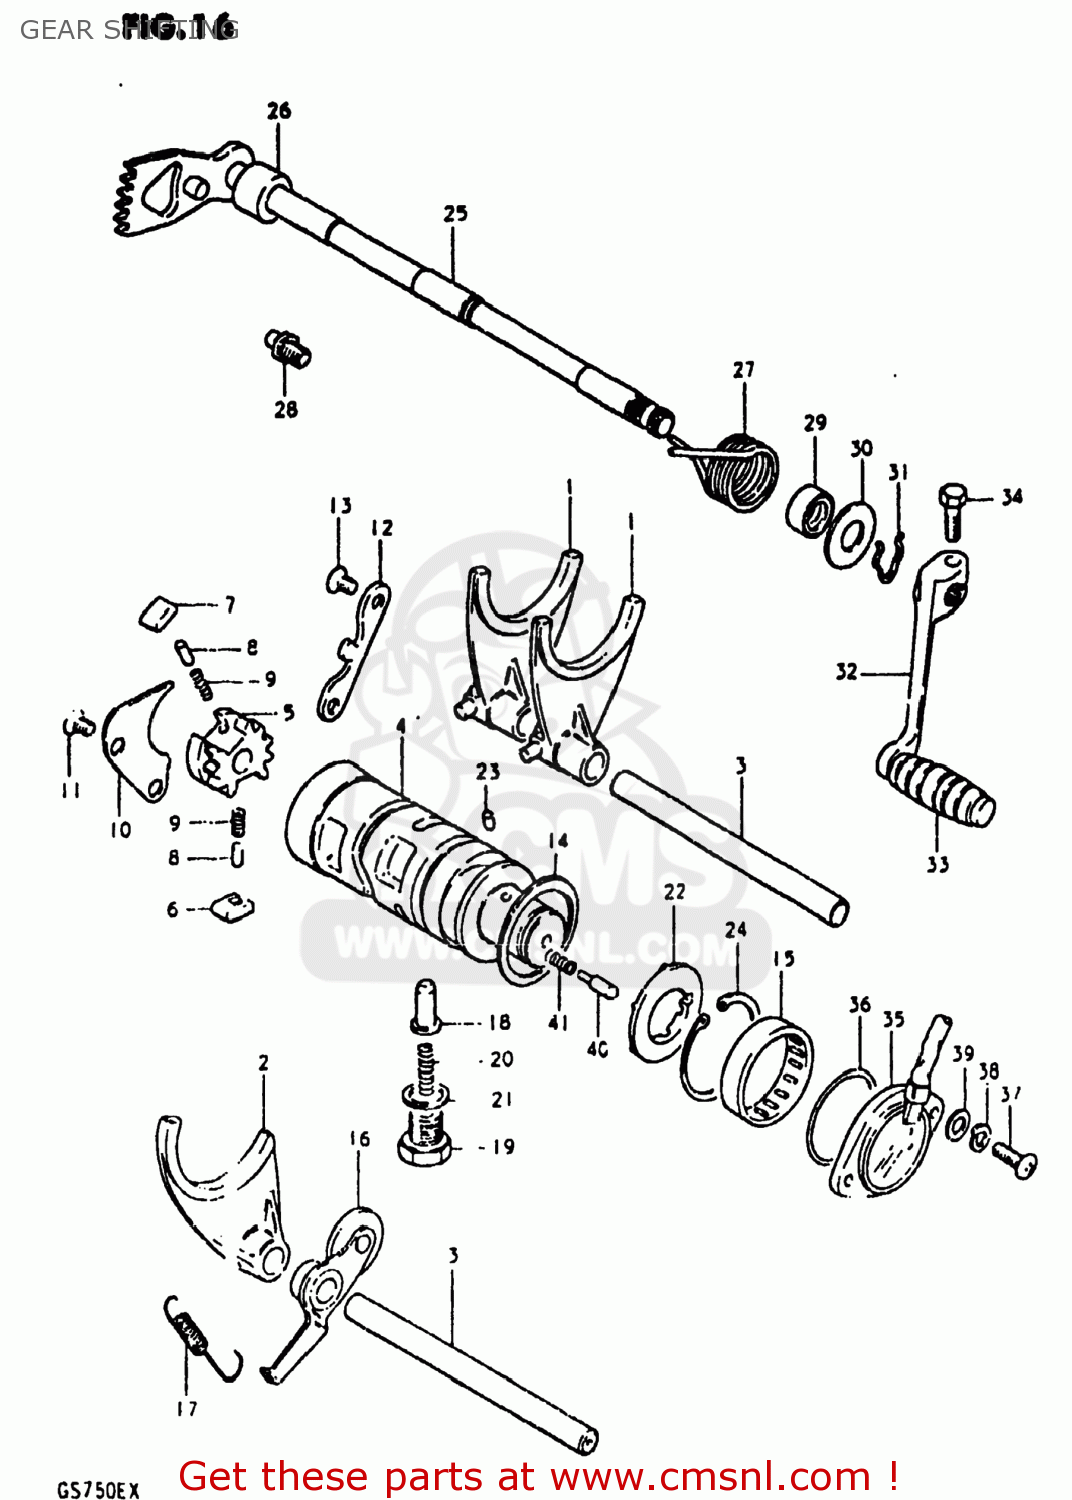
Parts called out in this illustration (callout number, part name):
1	FORK,GEAR SHIFT NO.1
2	FORK,GEAR SHIFT NO.3
3	SHAFT,GEAR SHIFT FORK
4	CAM,GEAR SHIFT
5	RETAINER,GEAR SHIFT CAM
6	PAWL,GEAR SHIFT NO.1
7	PAWL,GEAR SHIFT NO.2
8	PIN(5X8)
9	SPRING
10	LIFTER,GEAR SHIFT PAWL
11	SCREW
12	GUIDE,GEAR SHIFT CAM
13	SCREW
14	WASHER(40X45X1)
15	BEARING(25X32X12)
16	STOPPER,GEAR SHIFTING
17	SPRING
18	STOPPER,GEAR SHIFT CAM NO.2
19	HOLDER,GEAR SHIFT CAM STOP SPR
20	SPRING
21	GASKET(14X19.2X2) (NAS)
22	PLATE,GEAR SHIFT CAM STOPPER
23	PIN 4X6
24	CIRCLIP
25	SHAFT,GEAR SHIFT
26	SPACER(12X20X15.3)
27	SPRING
28	STOPPER,GEAR SHIFT CAM
29	OIL SEAL
30	WASHER (12.5X27X1.6)
31	SPRING,RETAINER
32	LEVER ASSEMBLY,GEAR SHIFTING
33	RUBBER,GEAR SHIFT PEDAL
34	BOLT
35	TERMINAL BASE ASSY,GEAR SHIFT
36	O-RING (D:2.4 ID:26.2)
37	SCREW 5X20
38	LOCK WASHER
39	WASHER
40	PIN(5X15.5)
41	SPRING
